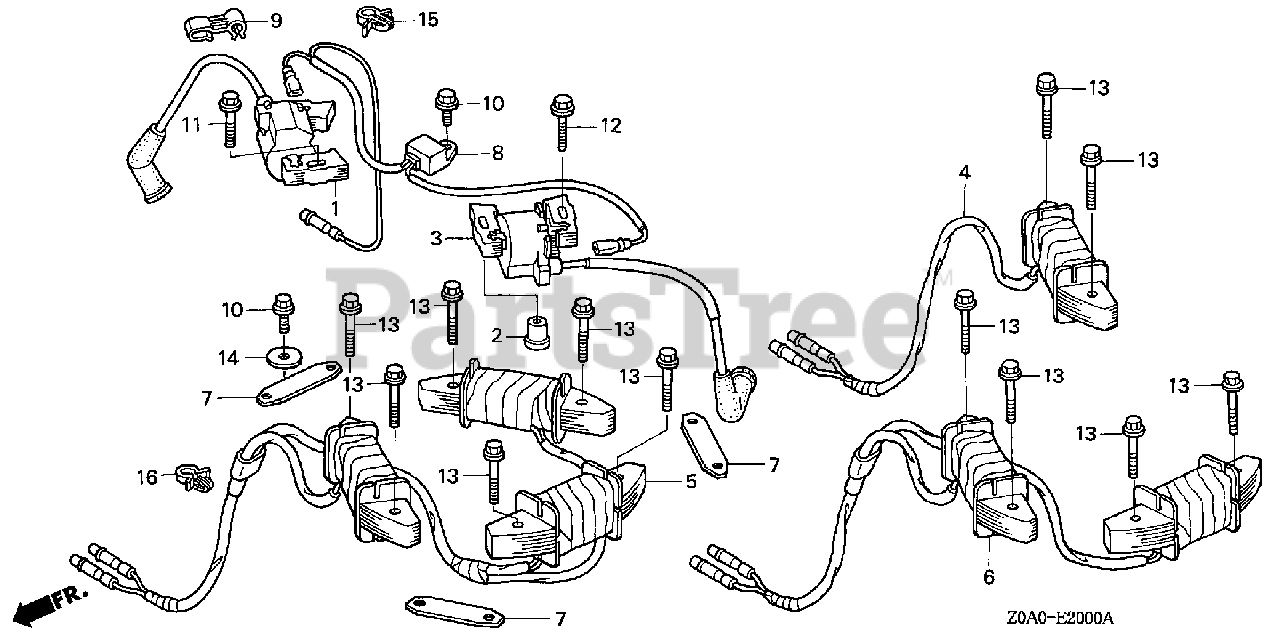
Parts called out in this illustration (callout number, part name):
1	COIL ASSY., IGNITION (#1)
2	COLLAR, IGNITION COIL
3	COIL ASSY., IGNITION (#2)
4	COIL ASSY., CHARGE (12V-3A)
8	DIODE ASSY., ENGINE STOP
9	CLAMP, CENTER CORD
10	BOLT, FLANGE (6X12) (CT200)
11	BOLT, FLANGE (6X28)
12	BOLT, FLANGE (6X45)
13	BOLT, FLANGE (6X32)
14	WASHER, TANK SETTING
15	CLIP, WIRE HARNESS (6MM) (WHITE)
16	CLIP, WIRE HARNESS
